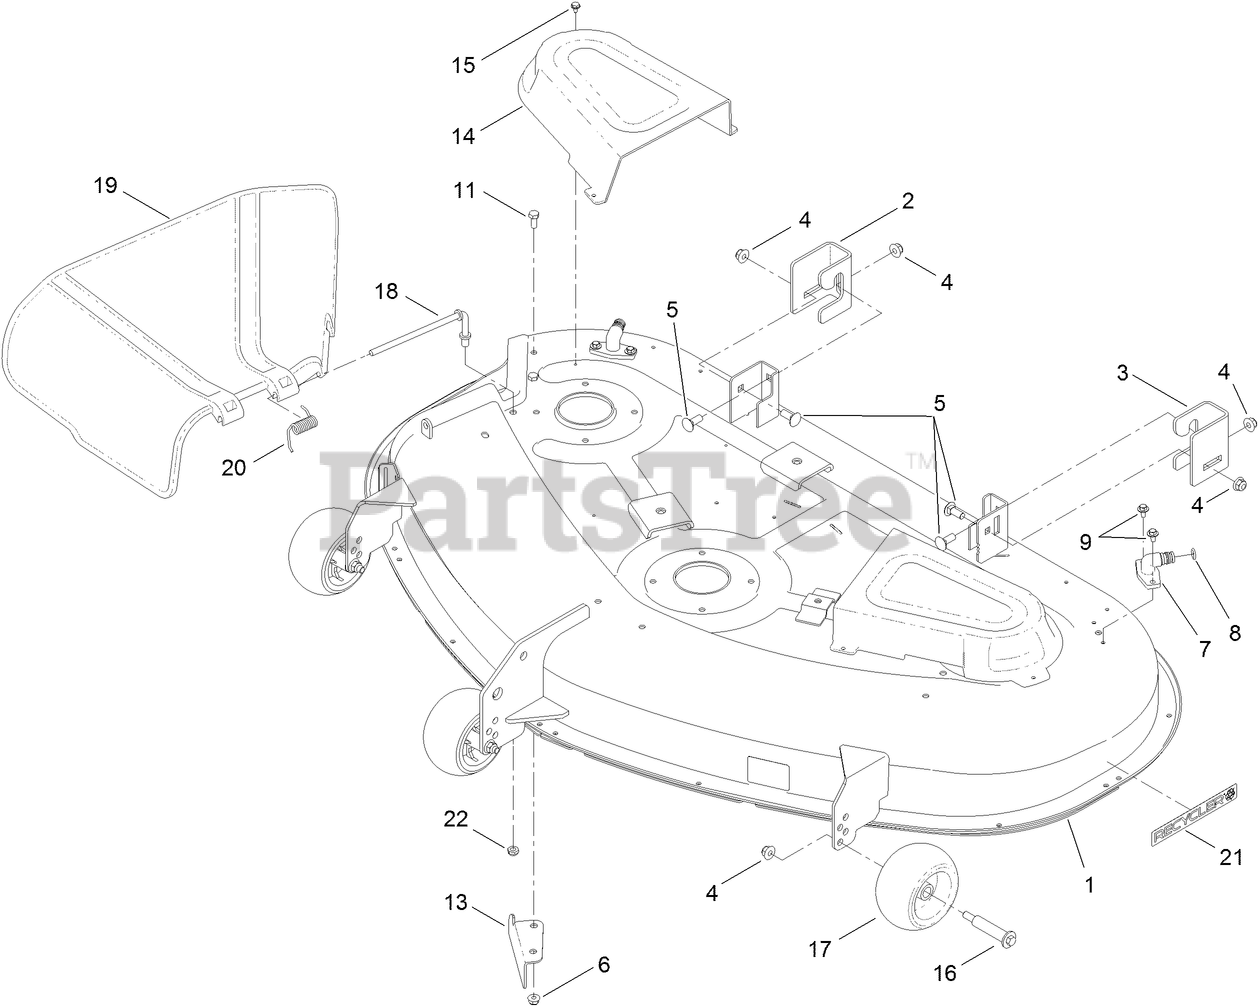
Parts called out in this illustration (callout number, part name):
1	50 INCH DECK AND DECAL ASM
3	BRACKET-HANGER, LH
4	NUT-HF, NI
5	BOLT-CARR
6	NUT-HF, NI
8	O-RING
9	SCREW-HHFTF
11	SCREW-HH
13	BAFFLE-CUTOFF
14	COVER-BELT
15	SCREW-HWHTF
16	BOLT-SHOULDER
17	ROLLER-SCALP, ANTI
18	ROD-PIVOT
19	DEFLECTOR
20	SPRING-TORSION
21	DECAL-RECYCLER
